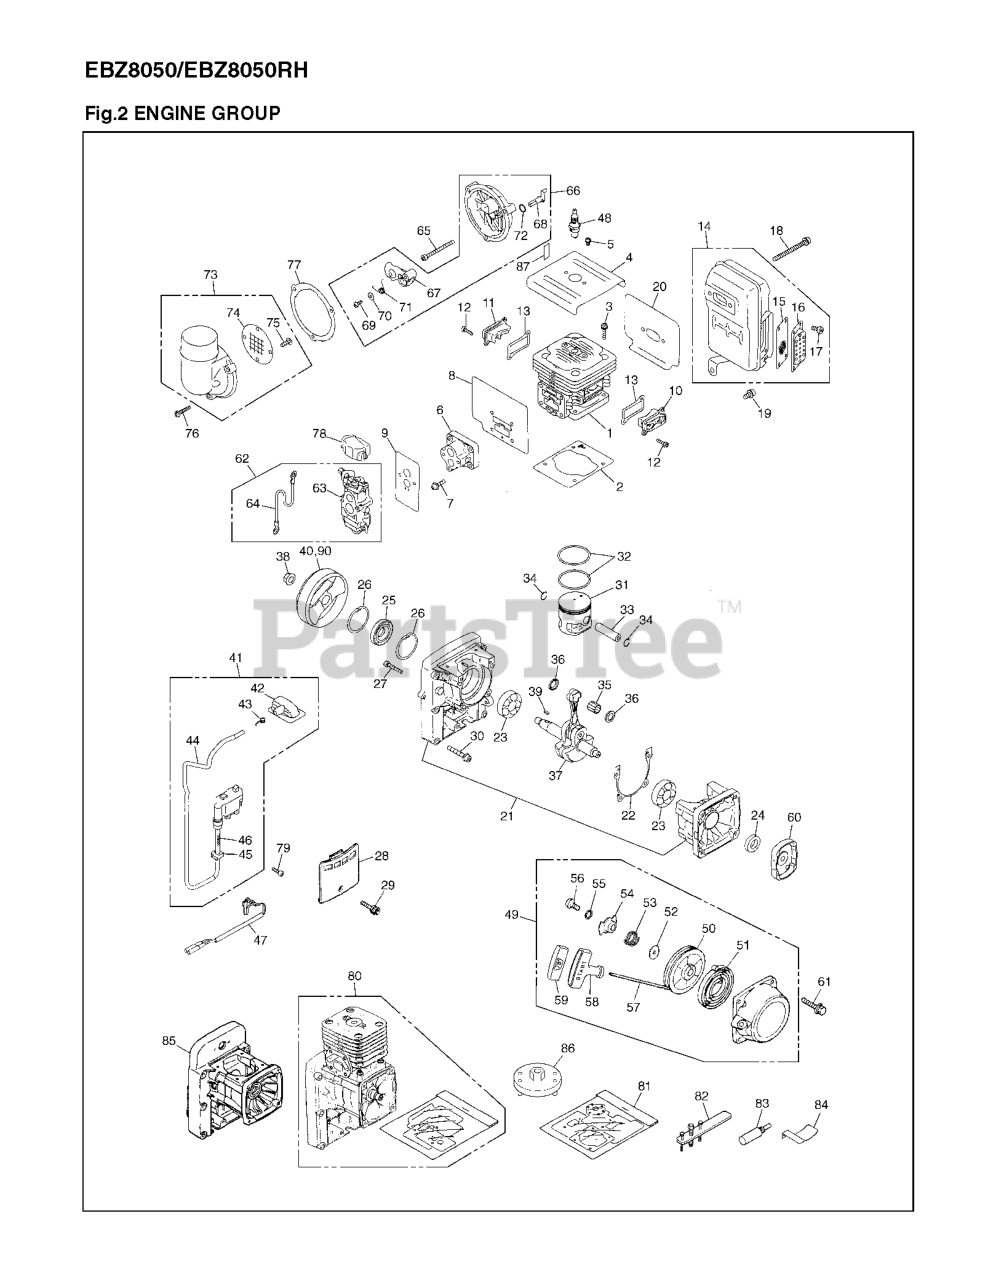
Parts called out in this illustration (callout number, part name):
1	CYLINDER
2	GASKET
3	BOLT
4	PLATE
6	INSULATOR
8	GASKET
10	RP_COVER TR(S)
11	COVER TR(F)
14	MUFFLER-A
15	%ARRESTER
16	RP_DIFFUSER
20	GASKET MUFFLER
21	CRANKCASE COMP.
22	GASKET
23	BALL BEARING
24	SEAL
25	SEAL
26	SNAP-RING
28	COVER
30	BOLT
32	PISTON RING (1-PER BOX)
33	PISTON PIN
34	SNAP RING
35	ROLLER BEARING
37	SHAFT COMP
39	KEY
40	ROTOR
41	COIL ASSY.(RPLS 848H107120)
41	COIL ASSY
43	SPRING
44	RP TUBE-A
45	GROMMET
46	RP TUBE-A
47	CORD-COMP
48	PLUG CMR7H
49	RECOIL ASSY
50	REEL
52	WASHER
53	SPRING FRICTION
54	PLATE
57	ROPE
58	KNOB
59	COVER
60	PULLEY ASSY
62	CARBURETOR SET
63	CARBURETOR-A
64	CORD
66	CUP ASSY
67	CHOKE PLATE
69	SCREW
70	RP_WASHER
73	CUP COVER ASSY
74	SCREEN
75	SCREW
80	SHORT BLOCK
81	GASKET KIT
82	PULLER ASSY
85	RP_CRANKCASE-A
86	RP_PULLER
87	LABEL,CHOKE
90	ROTOR
